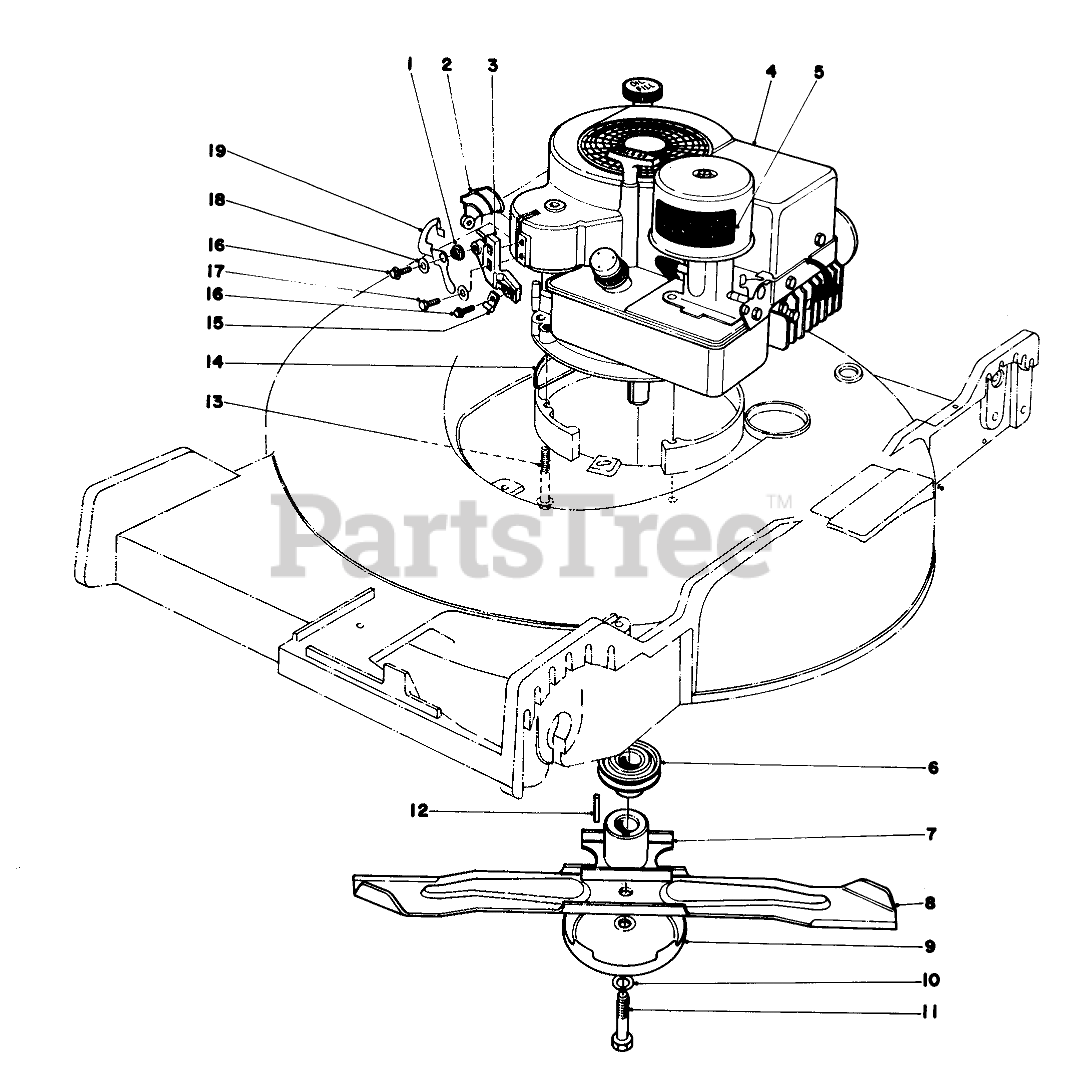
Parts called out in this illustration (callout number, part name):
1	BUSHING
2	INTERLOCK LEVER
3	CABLE & PIVOT BLOCK
4	Engine
5	Air Cleaner Decal
6	DRIVER PULLEY
7	Blade Retainer
8	Blade
9	AntiScalp Cup
10	WASHER-LOCK
11	SCREW-BLADE
12	KEY-SQUARE
13	3/8-16 X 2-3/4 CAPSCR
14	HOUSING CAP
15	CLAMP
16	SCREW-HWHTF
17	SCREW-HH
18	WASHER-FLAT
19	CAM INTERLOCK
